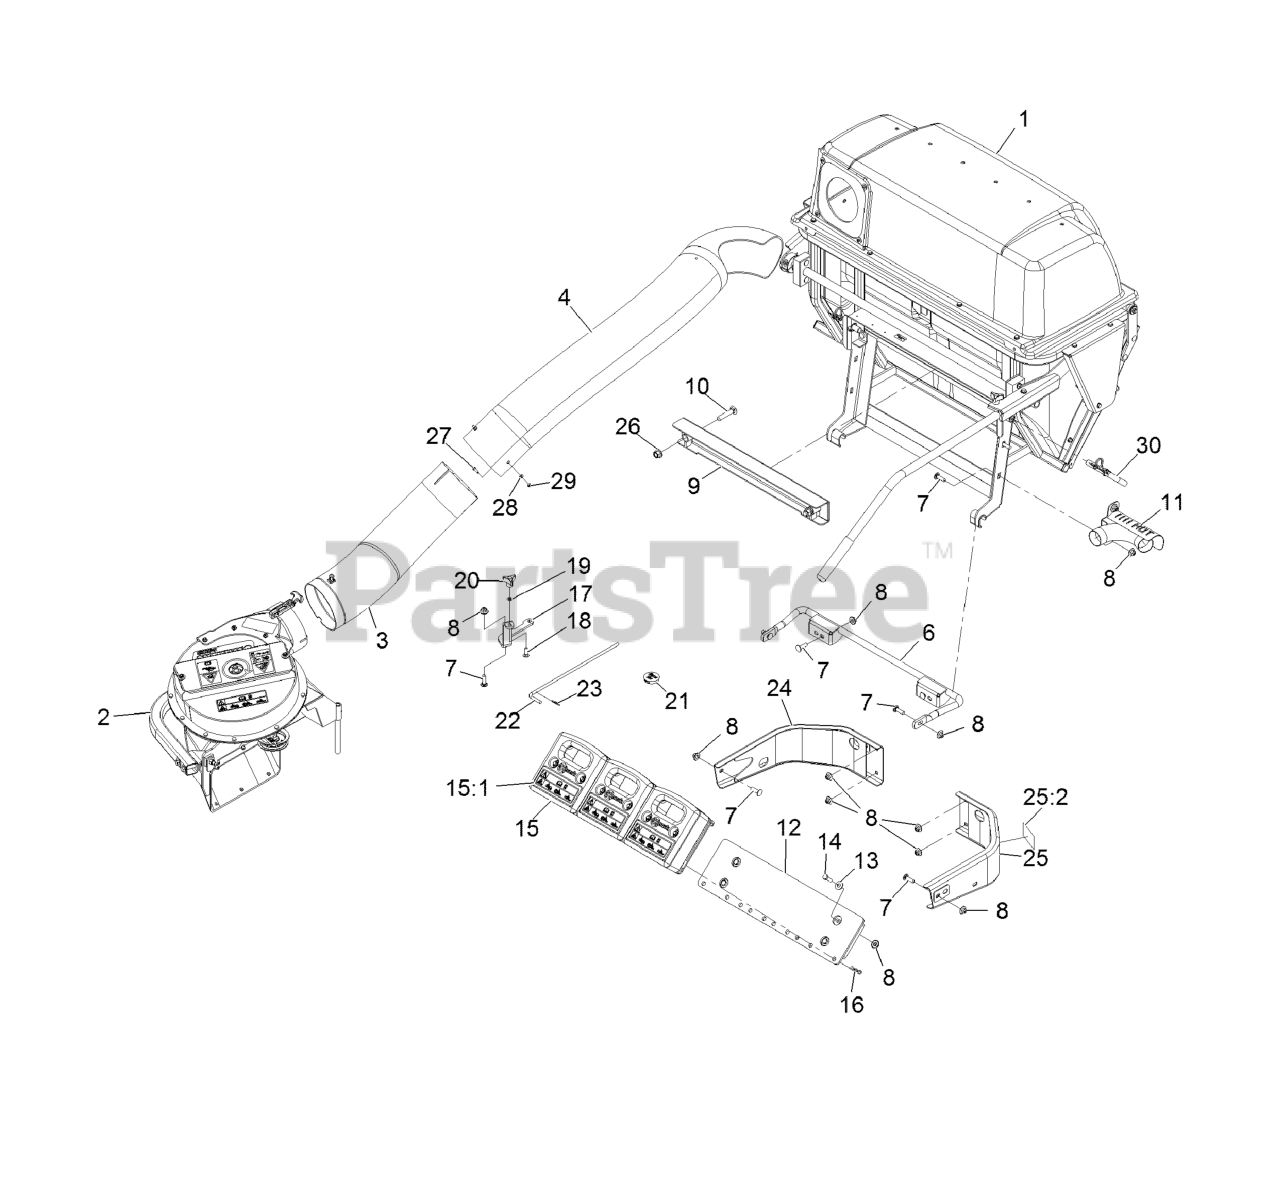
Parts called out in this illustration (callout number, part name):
1	ASM,Hopper Sm Qds
2	ASM, BLOWER SMALL - SVC ONLY
3	LOWER TUBE ASM
4	TUBE-UPPER
6	MOUNT-BAGGER, LOWER
7	Bolt-Carriage 3/8-16 X 1 1/4
8	Nut-Nyloc 3/8-16 Flg
9	MOUNT-BAGGER, UPPER
10	SCREW-CARR
11	EXHAUST DIVERTER ASM
12	WLD, MOUNT TOEBOARD WEIGHT
13	WASHER-FLAT
14	SCREW-HH
15	ASM,CAST WEIGHT
15:1	DECAL-WARNING WEIGHT
16	PIN-HAIR
17	BRACKET, SMALL UV BELT COVER
18	BOLT-CARR
19	RING-RETAINING, BOLT
20	KNOB-3 PRONG
21	PLUG, BLACK NYLON 1.75
22	PIN,CHUTE PIVOT
23	PIN-COTTER
24	BUMPER-RH
25	LH BUMPER ASM
25:2	DECAL-WARNING
26	Nut-Lock 1/2-13
27	SCREW-HWH
28	WASHER-FLAT
29	NUT-LOCK, NI
30	PIN-MOUNT, BAGGER
